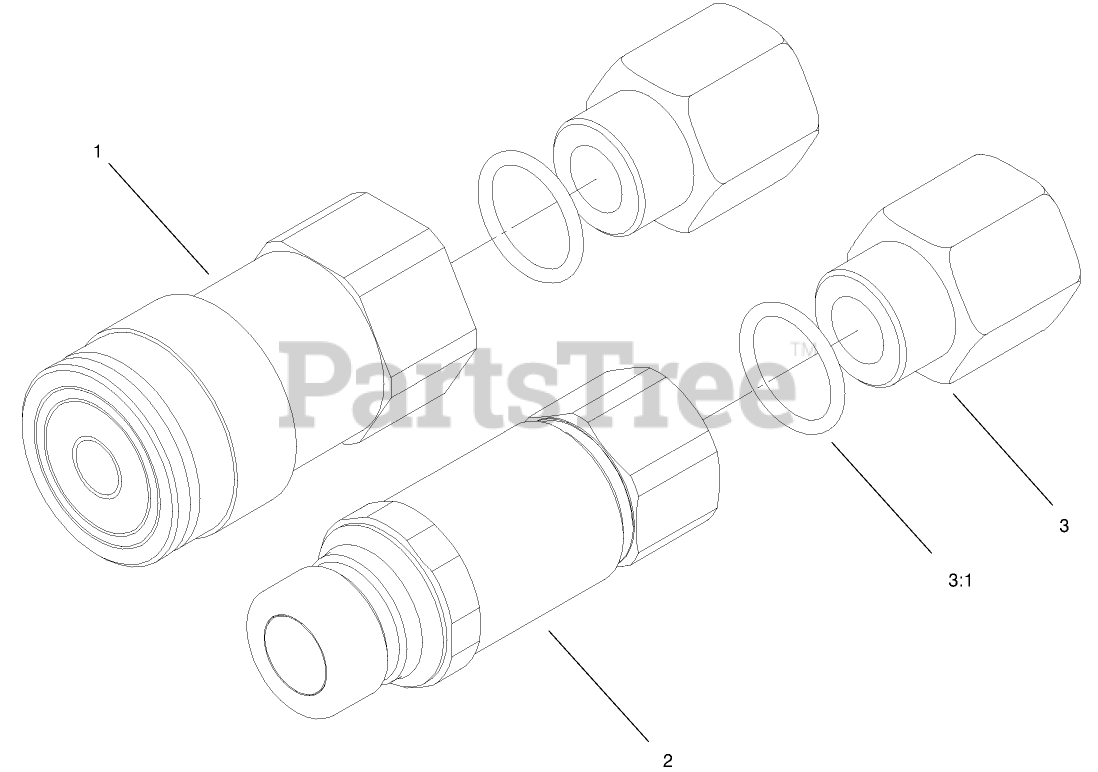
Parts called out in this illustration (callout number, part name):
1	COUPLER-FACE, FLUSH
2	NIPPLE-CONNECT, PRESSURE
3	ADAPTER-HYD
3:1	O-RING
